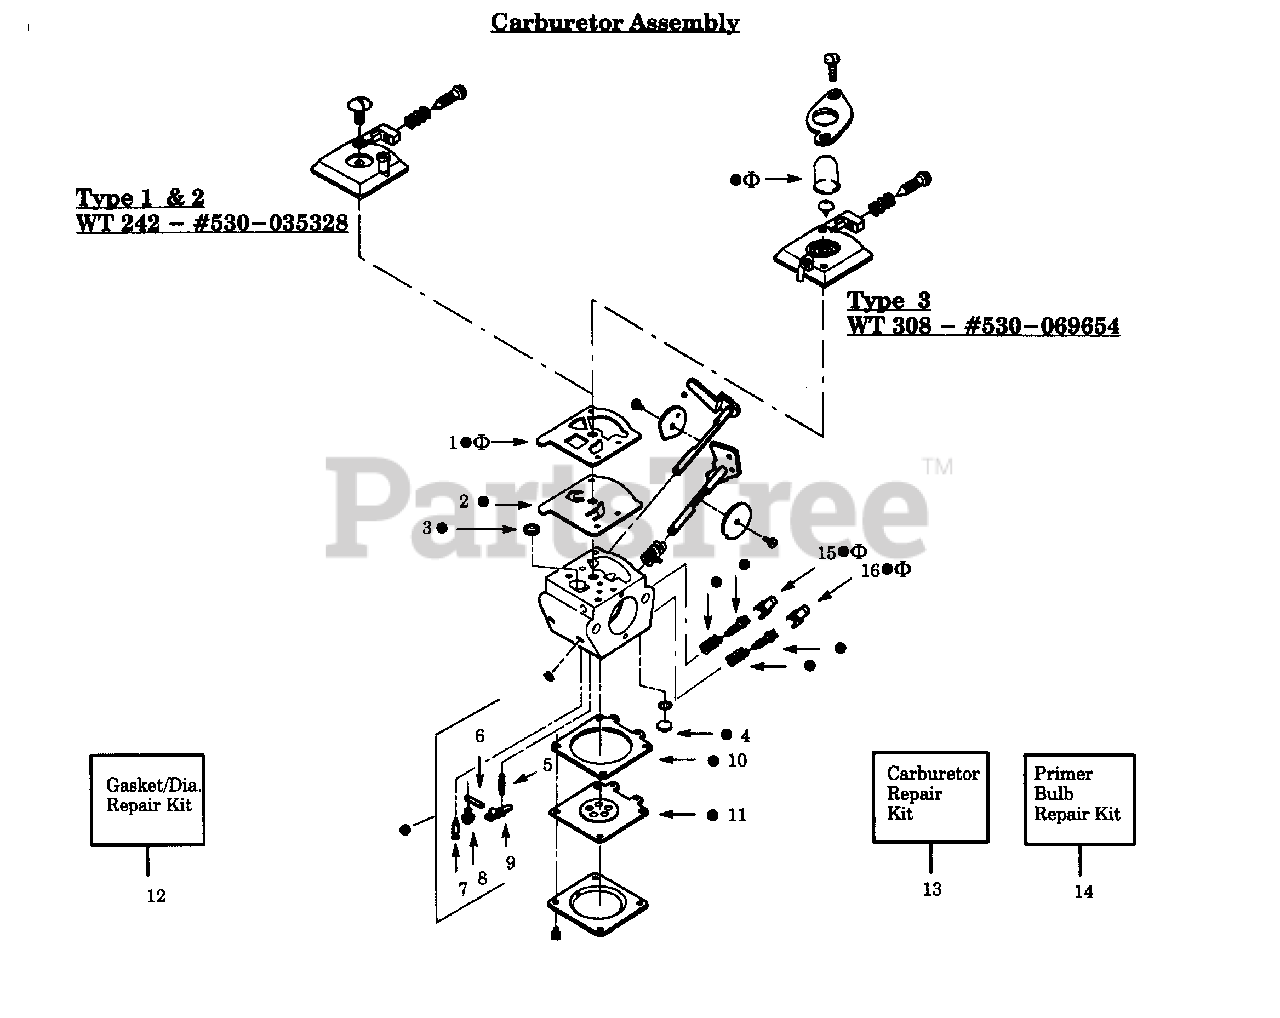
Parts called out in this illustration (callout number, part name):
1	Pump Gasket Types 1 & 2
2	Pump Diaphragm Types 1 & 2
3	Fuel Inlet Screen Types 1 & 2
4	Welch Plug Types 1 & 2
5	Metering Lever Spring Types 1 & 2
6	Metering Pin Types 1 & 2
7	Inlet Needle Valve Types 1 & 2
8	Metering Lever Pin Screw Types 1 & 2
9	Metering Lever Types 1 & 2
10	Metering Diaphragm Gasket Types 1 & 2
11	Metering Diaphragm Types 1 & 2
12	Gasket/Diaphragm Kit
13	Carburetor Repair Kit Type 1 & 2
13	Type 3
15	Limiter Cap-Low Type 3
16	Limiter Cap-High Type 3
